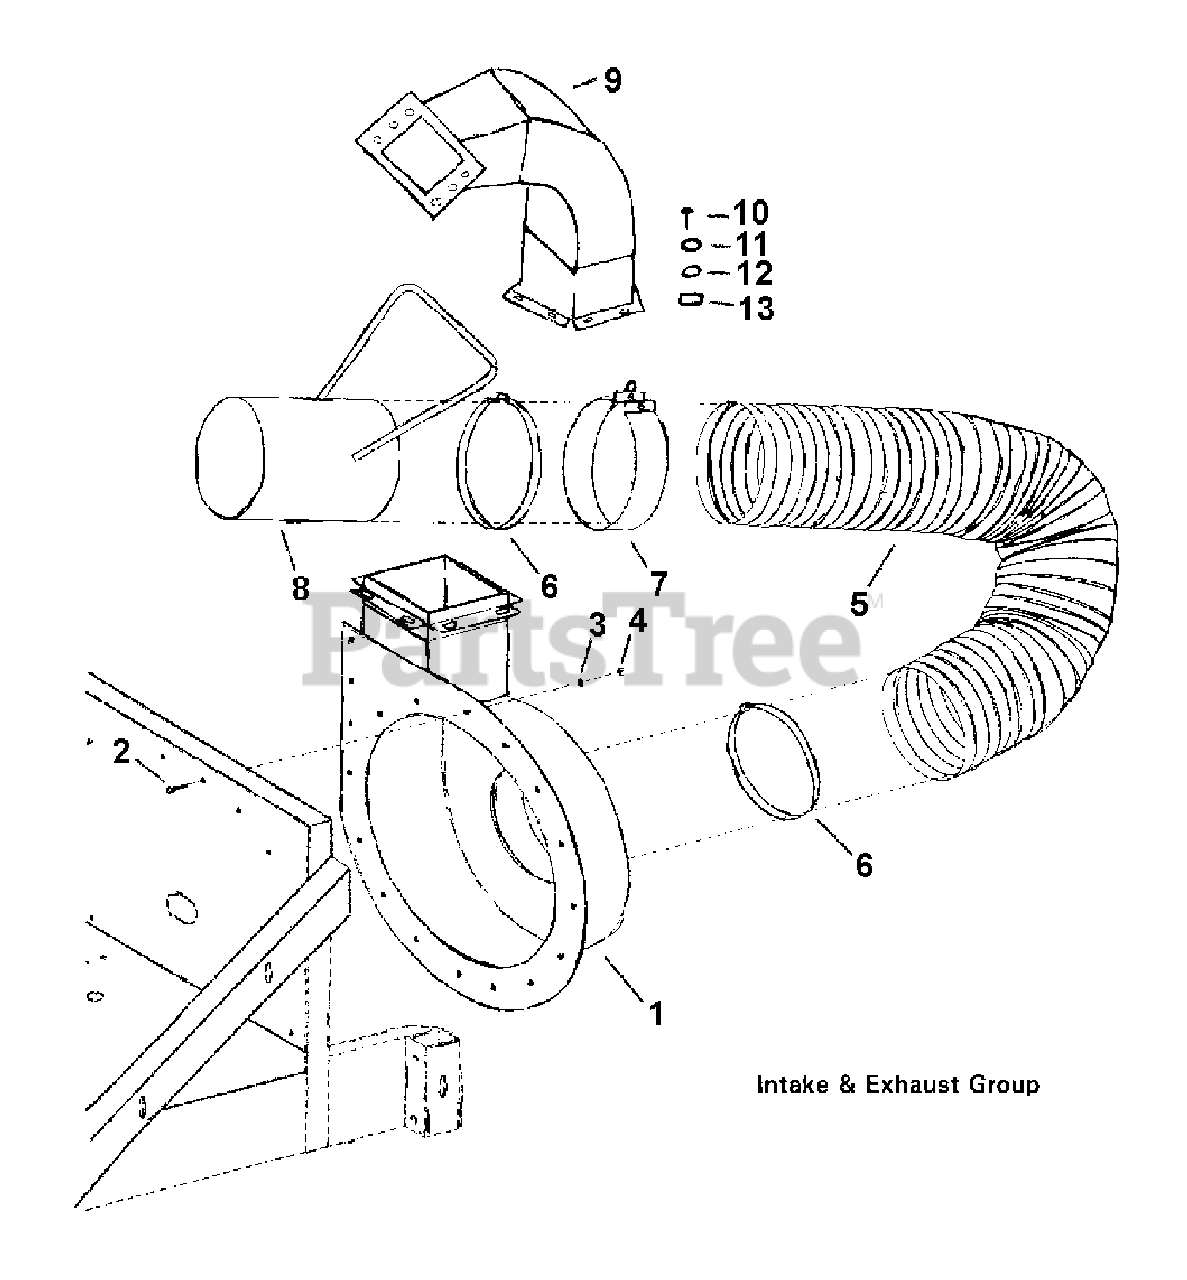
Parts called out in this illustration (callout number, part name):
1	Housing, Impeller - Complete with Liner Kit Below
2	3/8-16x1 Hex Bolt
3	3/8 Lock Washer
4	3/8-16 Hex Nut
5	Hose, Intake 12"x10'
6	Clamp, Hose 12"
7	Band, Hose Support 12" with Hardware
8	Nozzle, Intake 12" w/Adjustable Handle
9	Discharge Elbow
10	3/8-16x1-1/4 Hex Bolt
11	3/8 Flat Washer
12	3/8 Lock Washer
13	3/8-16 Hex Nut
